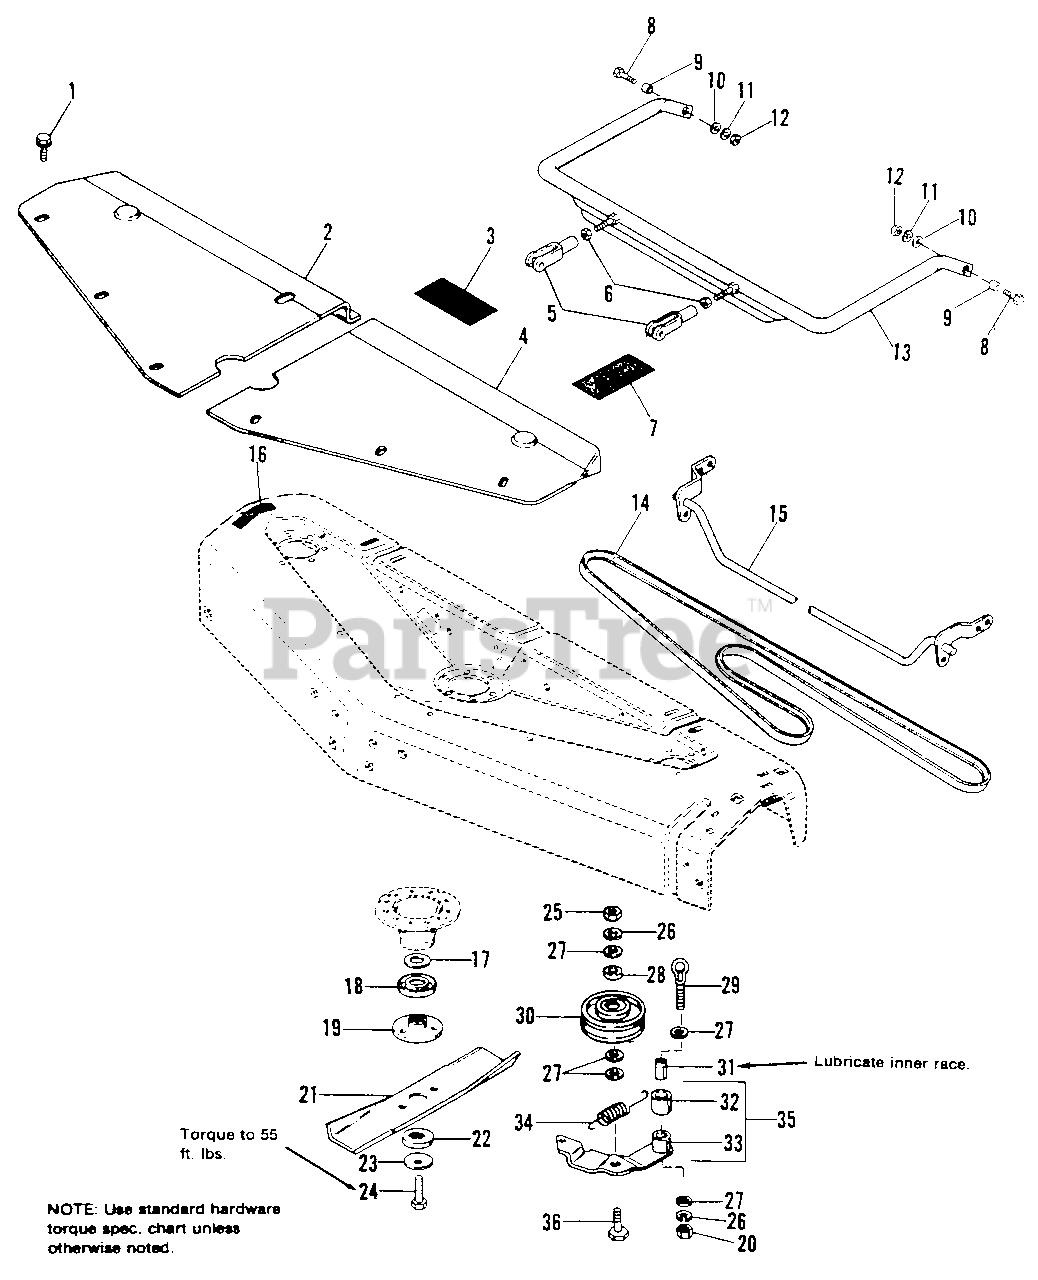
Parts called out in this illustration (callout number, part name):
1	SCREW. Hex, Taptite, 1/4-20 x 3/8
2	COVER. R.H.
3	DECAL, Belt Installation
4	COVER. L.H.
6	NUT, Hex, Jam, 1/2-20
7	DECAL, Danger
8	CAPSCREW, Hex Hd., 1/2-13 x 1-1/4
10	WASHER. Plain, 7/16
11	LOCKWASHER, 1/2
12	NUT, Hex, Full, 1/2-13
14	BELT, "V", Arbor Drive
15	ROCKER ARM ASSY.
16	DECAL, Danger
17	WASHER, Shim
18	SHIELD. Grass
19	ADAPTOR, Blade
20	NUT, Hex, 3/8-16
21	BLADE. 48" Mower
22	WASHER, Spline
23	WASHER, Spring
24	CAPSCREW, Hex Hd., 7/16-14 x 1
25	NUT, Hex, Jam, 3/8-16
26	LOCKWASHER, 3/8
27	WASHER, Plain, 5/16
30	PULLEY ASSY.
31	RACE, Inner
35	LEVER ASSY., Idler (w/Bushing)
36	CAPSCREW, Hex Hd., 3/8-16 x 1-1/4
